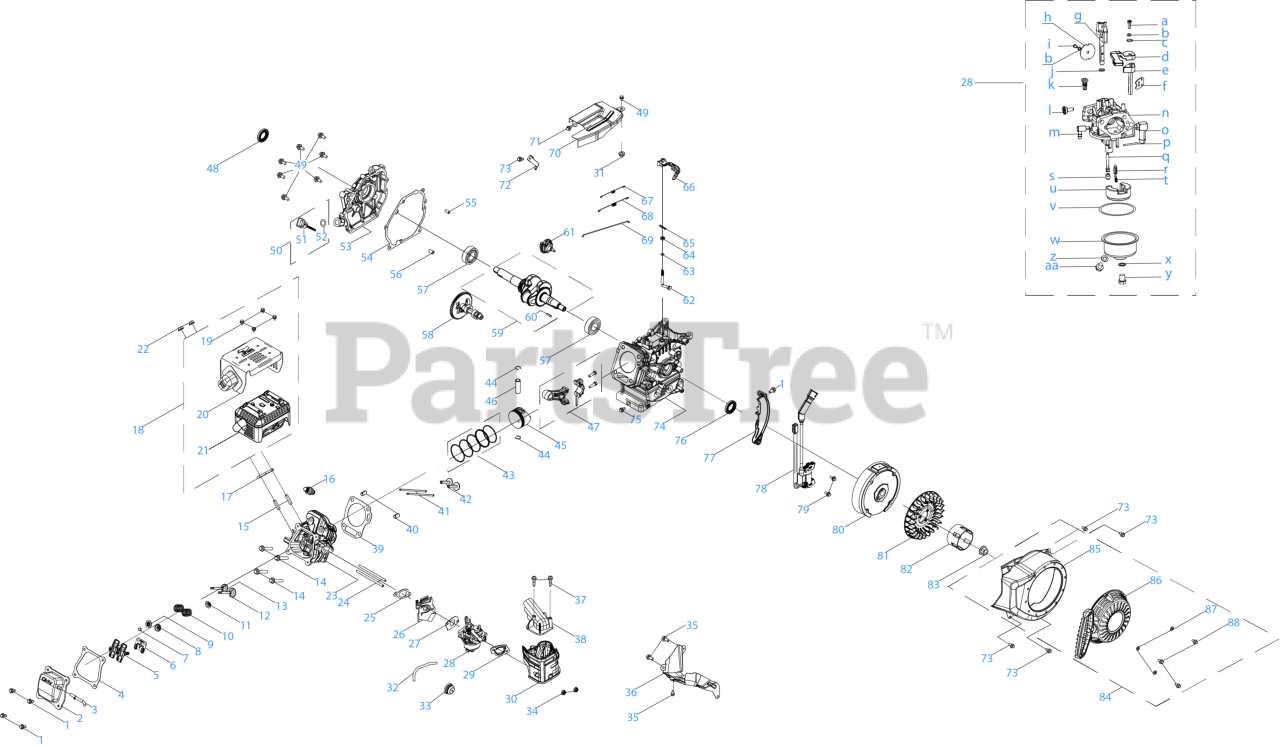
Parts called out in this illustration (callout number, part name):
1	BOLT M6 x 16
2	VALVE COVER
3	BREATHER HOSE
4	VALVE COVER GASKET
5	ROCKER ARM ASSEMBLY
6	ROCKER ARM BASE
7	EXHAUST VALVE ADJUSTER
8	INTAKE VALVE SPRING RETAINER
9	EXHAUST VALVE SPRING RETAINER
10	VALVE SPRING
11	INTAKE VALVE SEAL
12	INTAKE VALVE
13	EXHAUST VALVE
14	BOLT M8 x 50
15	STUD M8 x 36
16	SPARK PLUG
17	MUFFLER GASKET
18	MUFFLER ASSEMBLY
19	BOLT M5-.8 x 8 CL10.9
23	CYLINDER HEAD
24	STUD M6-1 x 113
25	CARBURETOR INSULATOR GASKET
26	CARBURETOR INSULATOR
27	CARBURETOR GASKET
28	CARBURATOR
29	CARBURETOR GASKET PLATE
30	HEATER BOX HOUSING
31	HEX NUT
32	FUEL HOSE 3.2X6.5X530
34	HEX NUT
35	BOLT M6-1 x 10 GR8.8
36	SHROUD
37	BOLT M4.2 x 16
38	INTAKE HEATER BOX
39	CYLINDER HEAD GASKET
40	DOWEL PIN
41	SINGLE PUSH ROD
42	TAPPET
43	PISTON RING KIT
44	SNAP RING-PISTON PIN
45	PISTON
46	PISTON PIN
47	CONNECTING ROD ASSEMBLY
48	OIL SEAL
49	BOLT-M6-1 x 28 GR8.8
50	DIPSTICK ASSEMBLY
52	O-RING 15.8 x 2.5
53	CRANKCASE COVER
54	CRANKCASE COVER GASKET
55	DOWEL PIN
56	DOWEL PIN
57	BEARING
58	CAMSHAFT ASSEMBLY
59	CRANKSHAFT
60	FLYWHEEL KEY
61	GOVERNOR GEAR/SHAFT ASSEMBLY
62	GOVERNOR SHAFT
63	O-RING
64	GOVERNOR SEAL
65	COTTER PIN
66	GOVERNOR LEVER
67	GOVERNOR-RETURN SPRING
68	THROTTLE RETURN SPRING
69	GOVERNOR ROD
70	COVER SHIELD
71	BOLT M8-1.25 x 14 GR8.8
72	GOVERNOR SPRING BRACKET
73	BOLT M6-1 x 12 GR8.8
74	CRANKCASE
75	OIL PLUG 1/8 NPT
76	OIL SEAL
77	OIL ALERT SIDE PLATE
78	IGNITION COIL
79	BOLT M6-1 x 25 GR8.8
80	FLYWHEEL
81	COOLING FAN
82	STARTER CUP
83	FLYWHEEL NUT
84	RECOIL STARTER HOUSING
85	BLOWER HOUSING
86	RECOIL STARTER
87	RECOIL FLAT WASHER
88	BOLT M6 x 10
Z	FUEL DRAIN PLUG GASKET
